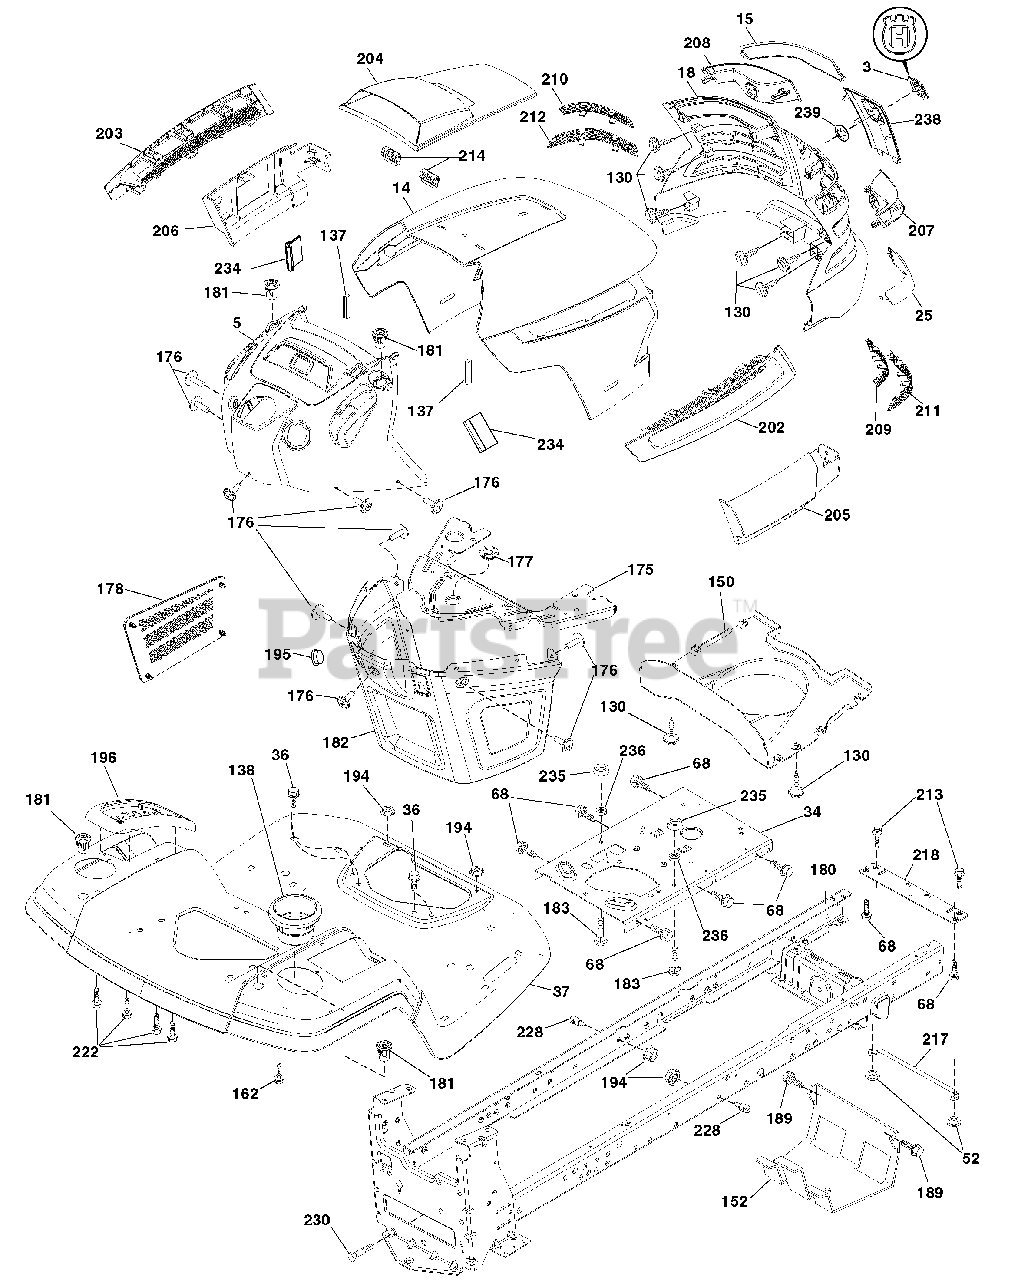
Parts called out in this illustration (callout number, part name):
3	Logo
4	Logo
14	Hood
18	Grille/Lens Asm.
34	Plate Engine
36	Screw 5/16-18 x 3/4
37	Fender
52	Nut Lock 5/16-18
68	Screw Thdrol 5/16-18 x 1/2
130	Screw 10 x 3/4 Single Lead-Hex
137	Bumper Dash
138	Cupholder
152	Shield Browning
175	Crossmember
176	Screw 10-24 x 5/8
177	Bushing Steering
178	Cargo Net Asm.
180	Chassis
181	Bushing Mtg. Fender Crgo
182	Dash Lower
183	Bolt Fin Hex 5/16-18 unc x 1-1/4
189	Screw 5/16-18 x 3/4
194	Nut Lock Hex Flange 5/16-18
195	Plug Hole Dash Lower
196	Console Asm. Deck Lift
202	Vent Side Hood RH
203	Vent Side Hood LH
204	Vent Top Hood
205	Skirt Hood Side RH
206	Skirt Hood Side LH
209	Insert Hex Top RH
210	Insert Hex Top Lh
211	Insert Hex Bottom RH
212	Insert Hex Bottom LH
213	Bolt 5/16-18 x 3/4
214	Clip Retainer Tinner
218	X-Piece Hood Stop
222	Screw Thdrol 1/4-20 x 5/8
228	Stud Fastner
230	Bolt Shoulder 5/16-18
234	Bumper Hood
235	Spacer Fender
236	Nut Lock 5/16-18 UNC
